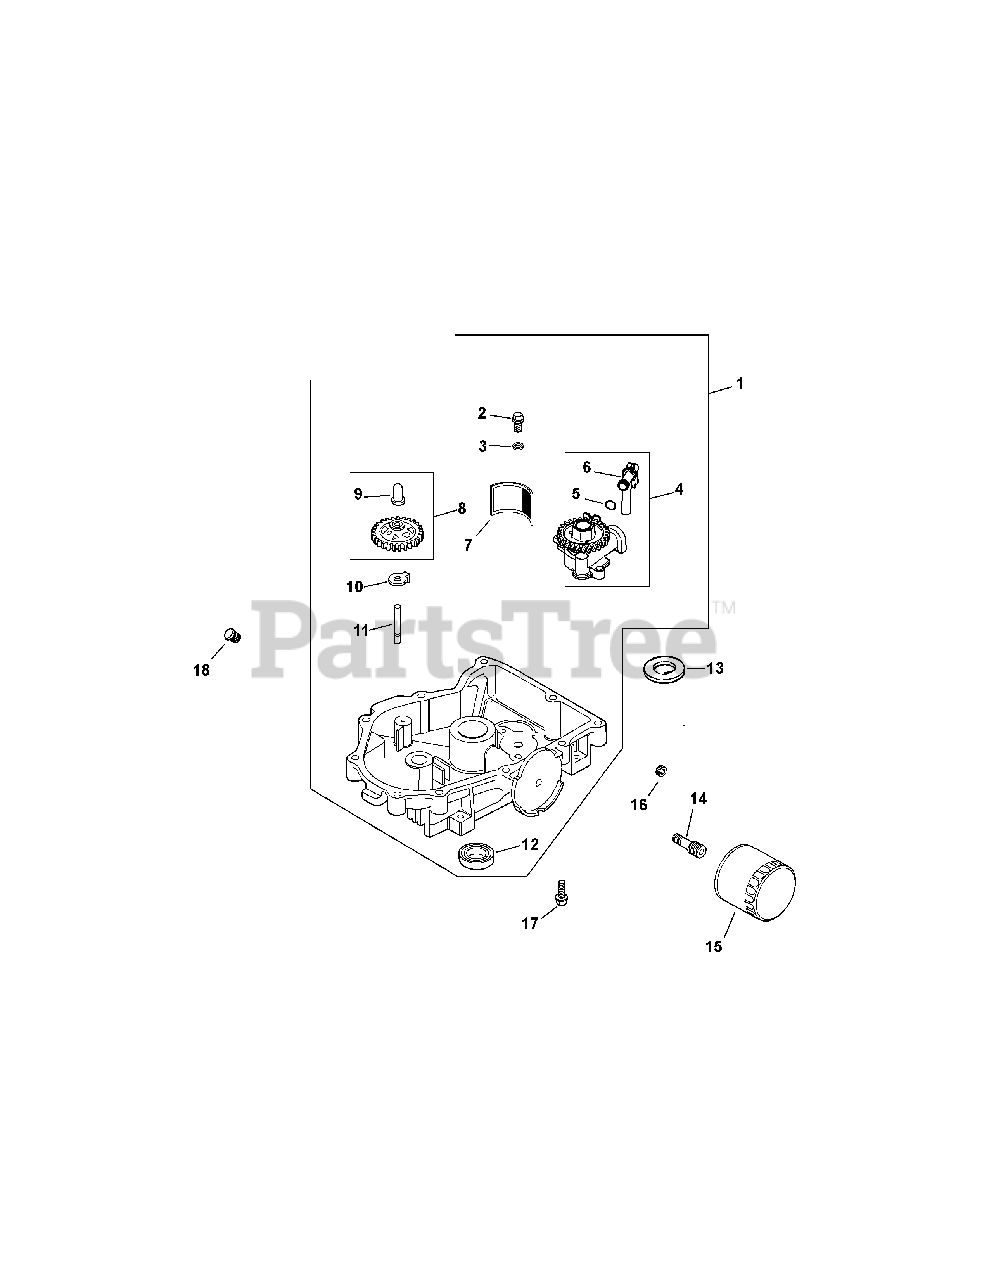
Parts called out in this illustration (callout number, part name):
1	OIL PAN ASSEMBLY (includes 2-12)
2	SCREW, FLG THD FRM M6X1.0X25
3	WASHER, FLAT 6 MM
4	KIT, OIL PUMP ASSEMBLY (includes 5, 6)
5	O-RING, OIL PICK-UP
6	KIT, OIL PICK-UP TUBE
8	KIT, GOVERNOR GEAR W/PIN (includes 9)
9	PIN, GOVERNOR REGULATING
11	SHAFT, GOVERNOR GEAR
14	NIPPLE, OIL FILTER
16	PLUG, PIPE CTSK 3/8''
17	SCREW, FLG M8X1.25X45
18	PLUG, HD PIPE 3/8''
